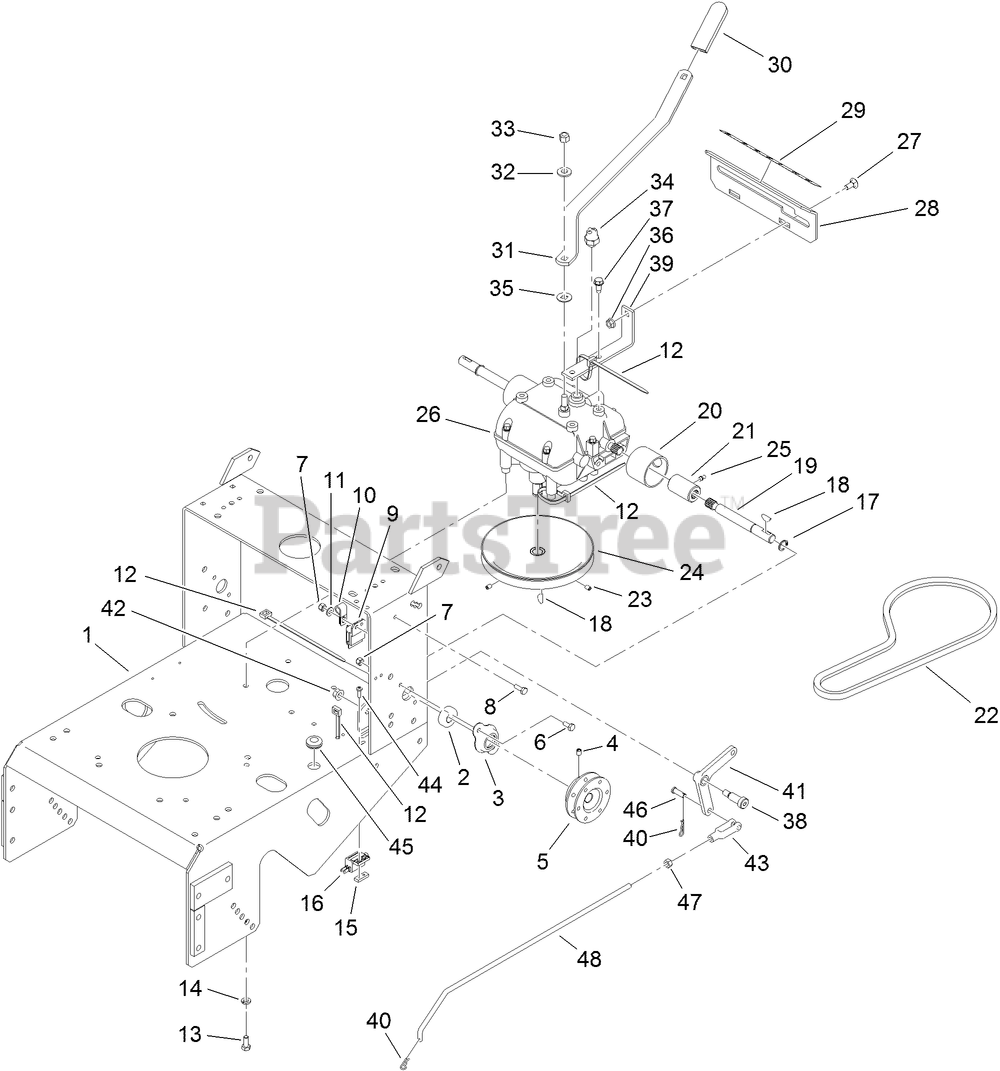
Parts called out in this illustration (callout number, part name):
1	FRAME-GEAR
2	BEARING-SHAFT
3	FLANGE-OUTPUT
4	SCREW-SET
5	SHEAVE-TRANSMISSION
6	SCREW-HH
7	NUT-LOCK, NI
8	SCREW-HH
9	MODULE-INTERLOCK
10	CLIP-LOOM
11	WASHER-FLAT
12	TIE-PLASTIC
13	SCREW-HH
14	WASHER-LOCK
15	PLATE-TAPPED
16	SWITCH-OPEN, NORMALLY
17	RING-RETAINING
18	KEY-WOODRUFF
19	SHAFT-TRANSMISSION
20	GUARD-COUPLER
21	COUPLER
22	V-BELT
23	SCREW-HSH
24	SHEAVE-TRANSMISSION
25	FITTING-GREASE
26	TRANSMISSION
27	BOLT-CARR
28	PLATE-SHIFT
29	DECAL-SPEED, GROUND
30	GRIP-LEVER
31	LEVER-SHIFT
32	WASHER-BELLEVILLE
33	NUT-LOCK
34	Switch-Start, Neutral
35	WASHER
36	NUT-HF
37	SCREW-HWH, THREAD CUT
38	BOLT-SHOULDER
39	BRACKET-PLATE, SHIFT
40	PIN-COTTER
41	BELLCRANK
42	NUT-HF
43	YOKE-ADJUSTABLE
44	SCREW-PPH
45	GROMMET
46	PIN-CLEVIS
47	NUT-HEX
48	ARM-ASSIST, LINKAGE
